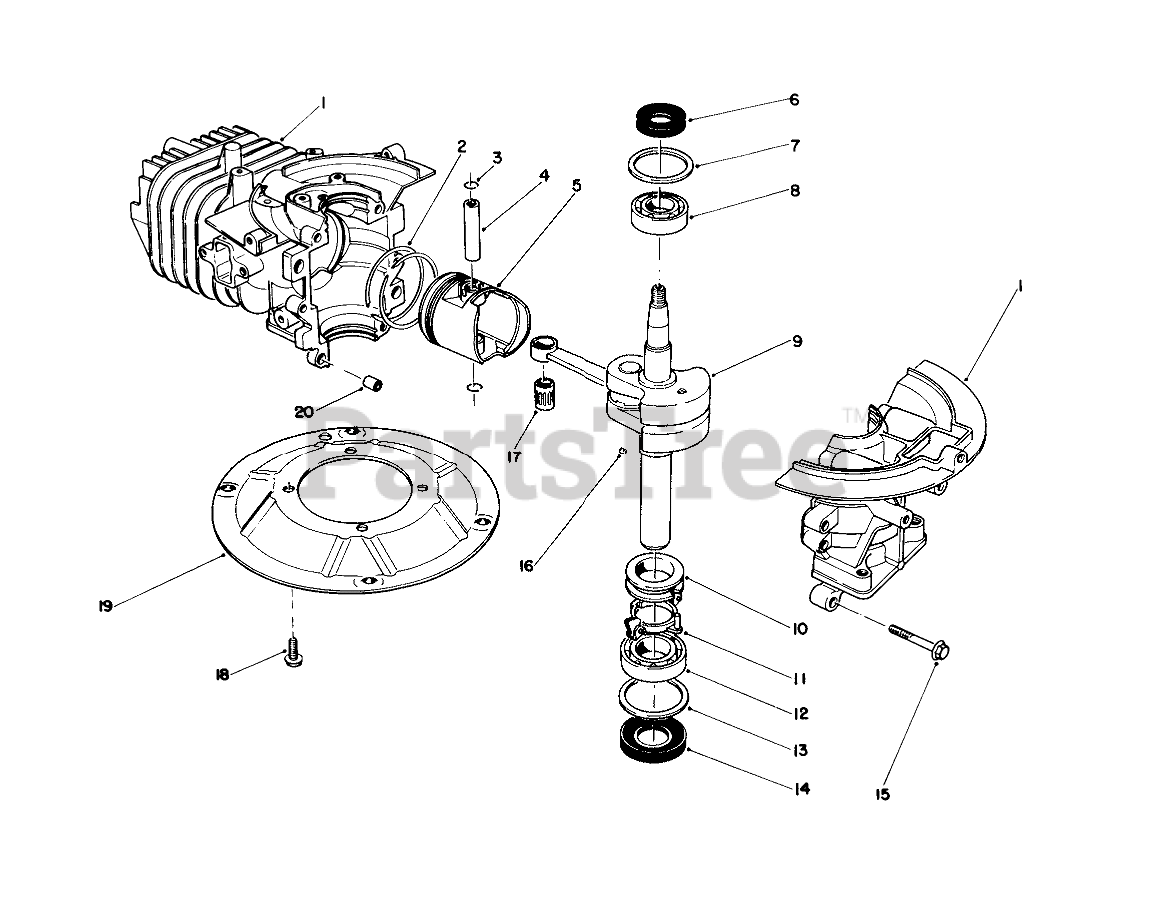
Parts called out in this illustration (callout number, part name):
1	CRANKCASE
2	RING SET
4	PIN-PISTON
5	Piston
6	OIL SEAL
7	WASHER-UPPER
8	BEARING-UPPER
9	Pin-Wrist
10	SPACER
11	BRACKET
12	LOWER BRG
13	WASHER-LOWER
14	SEAL-OIL
17	BEARING
19	PLATE-MOUNTING
